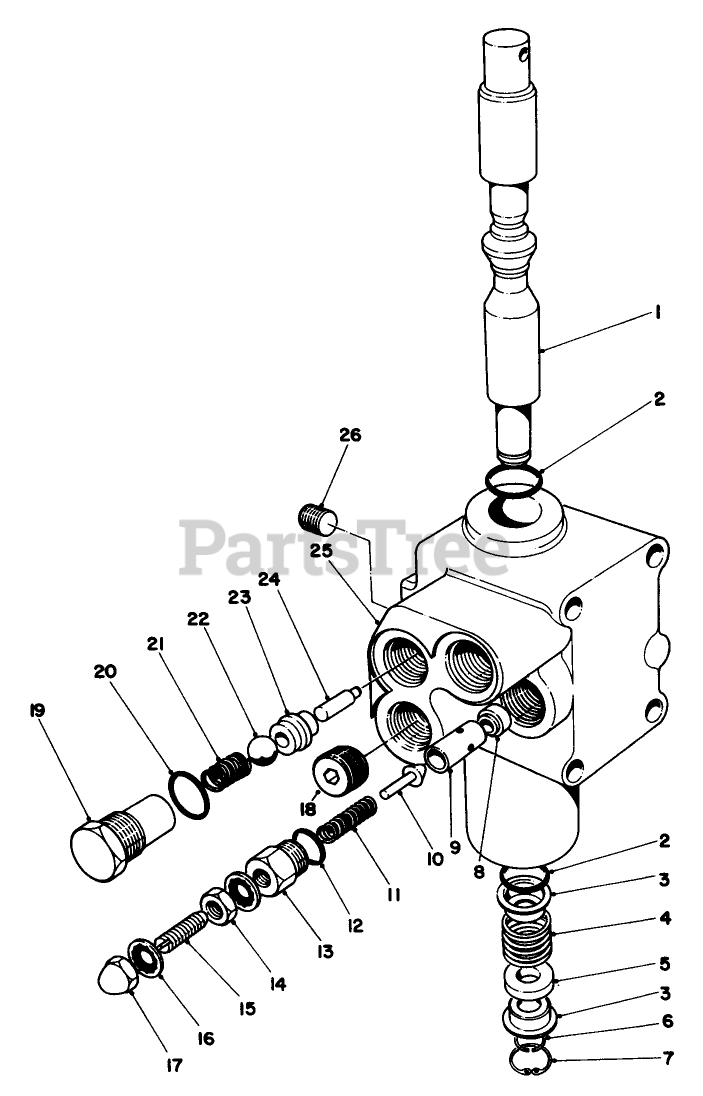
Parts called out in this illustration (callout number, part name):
1	SPOOL
2	O-RING
3	RETAINER
4	SPRING
5	FLOAT SPACER
6	RING-SNAP
7	RING-SNAP
8	VALVE SEAT (21-8550)
9	Guide
10	Plunger
12	"O" Ring
13	Cap-PV Adjustment
14	Jam Nut
15	Set Screw
16	Stat O-Seal
17	Nut-Acorn
20	O-RING
21	SPRING
23	SEAT-VALVE
26	Plug
